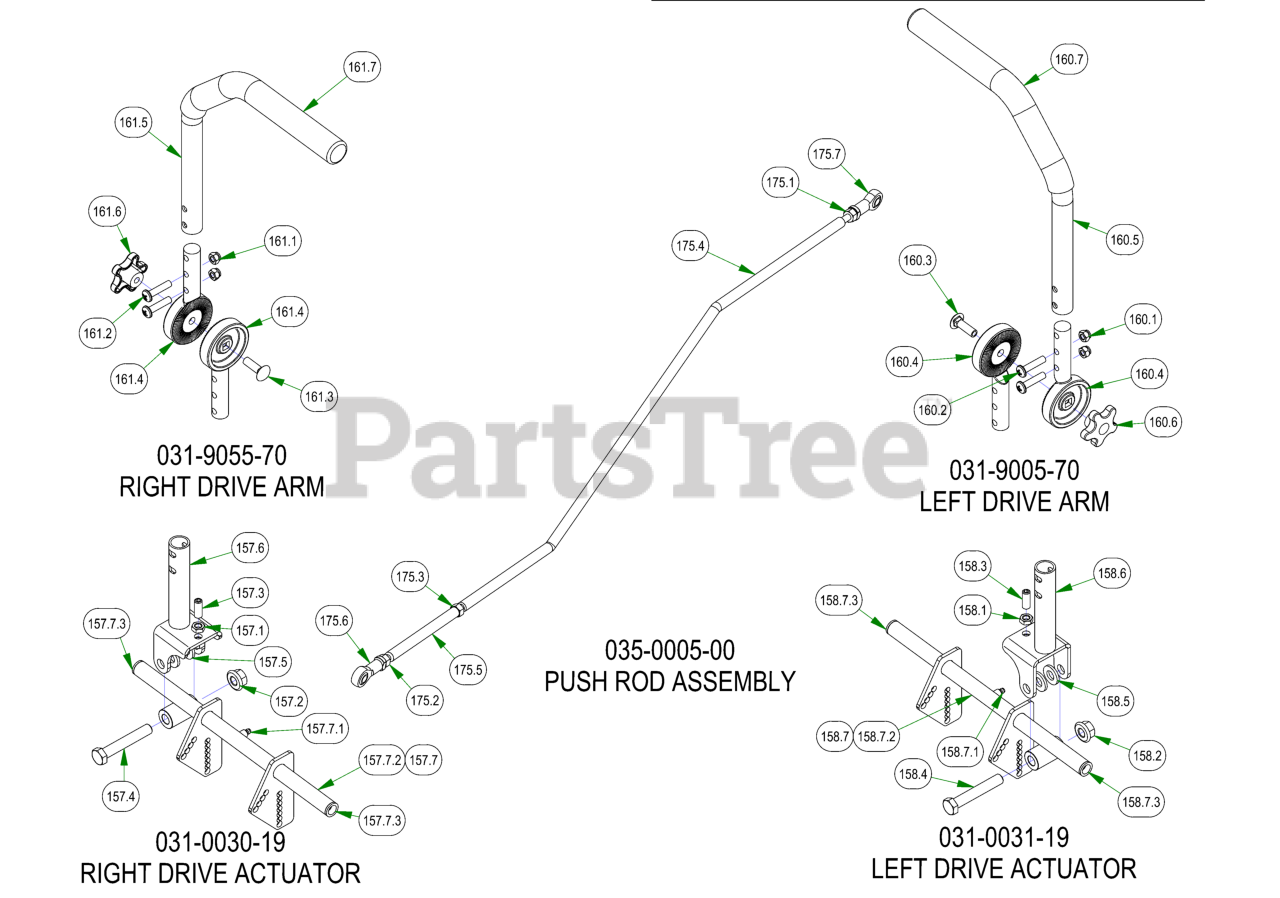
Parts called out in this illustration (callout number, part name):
157	2019 R Series RH Arm Rod Assembly
157.1	3/8-16 Half Jam Nut
157.2	1/2-13 NYLON INSERT FLANGE LOCKNUT ZINC
157.3	3/8-16 X 1 SOCKET SET SCREW (CUP POINT) PLAIN
157.4	1/2-13 X 3 HEX CAP SCREW (GR.5) ZINC
157.5	.505 ID X 1.000 OD X .125 THICK FLAT WASHER NYLON
157.6	Drive Arm Pivot
157.7	2019 Drive Arm Actuator right
157.7.1	1/4" Press in Grease Fitting
157.7.2	2019 Drive Arm Actuator right - Weldment
157.7.3	2019 Drive Arm Bushing
158	2019 R Series LH Arm Rod Assembly
158.1	3/8-16 Half Jam Nut
158.2	1/2-13 NYLON INSERT FLANGE LOCKNUT ZINC
158.3	3/8-16 X 1 SOCKET SET SCREW (CUP POINT) PLAIN
158.4	1/2-13 X 3 HEX CAP SCREW (GR.5) ZINC
158.5	.505 ID X 1.000 OD X .125 THICK FLAT WASHER NYLON
158.6	Drive Arm Pivot
158.7	2019 Drive Arm Actuator left
158.7.1	1/4" Press in Grease Fitting
158.7.2	2019 Drive Arm Actuator left - Weldment
158.7.3	2019 Drive Arm Bushing
160	2019 Left Hand ADJ. Steering Arm Kit
160.1	5/16-18 NYL INS L/N ZC
160.2	5/16-18 x 1 3/8" Futton Head Torx Drive Bolt
160.3	3/8-16 X 1-1/4 CARRIAGE BOLT ZINC
160.4	2019 Steering Arm Adjuster Casting
160.5	2019 Steering Arm Tube
160.6	Black Knob for Adjustable Steering Arm
160.7	Black Steering Arm Grip
161	2019 Right Hand ADJ. Steering Arm Kit
161.1	5/16-18 NYL INS L/N ZC
161.2	5/16-18 x 1 3/8" Futton Head Torx Drive Bolt
161.3	3/8-16 X 1-1/4 CARRIAGE BOLT ZINC
161.4	2019 Steering Arm Adjuster Casting
161.5	2019 Steering Arm Tube
161.6	Black Knob for Adjustable Steering Arm
161.7	Black Steering Arm Grip
175	2019 Renegade Push Rod Assembly
175.1	5/16" RH Fine Threaded Jam Nut
175.2	5/16" LH Fine Threaded Jam Nut
175.3	3/8" Fine Threaded Jam Nut
175.4	2019 Renegade Push Rod
175.5	2019 Renegade Push Rod Adjuster
175.6	Spherical Rod End - Outlaw
175.7	Spherical Rod End - Outlaw
